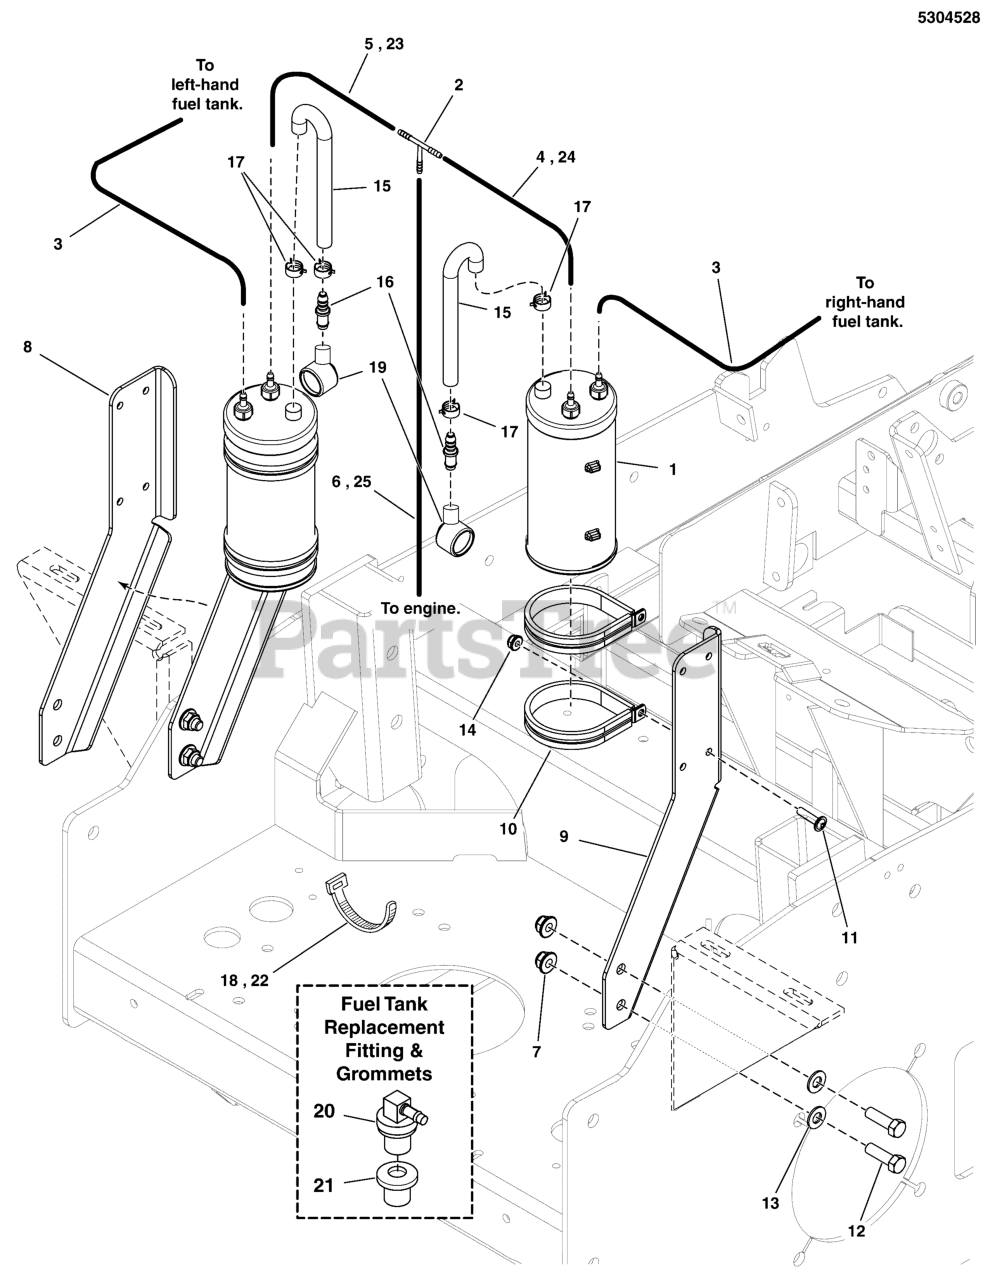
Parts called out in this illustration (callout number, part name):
1	CNSTR, CARB, 6 GAL
2	FITTING, 3/16" TEE, BARB TYPE, HDPE
3	HOSE, VAPOR, 5MM ID, 7.50 LG
4	HOSE, VAPOR, 5MM ID, 49.00 LG
5	HOSE, VAPOR, 5MM ID, 16.50 LG
6	HOSE, VAPOR, 5MM ID, 18.00 LG
7	NUT, 3/8-16 HEX NYLOCK FLANGE
8	BRACKET, EVAP MOUNT, LEFT - BLK
9	BRACKET, EVAP MOUNT, RIGHT - BLK
10	CLAMP, 3" ID, CUSHIONED, STAINLESS
12	BOLT, 3/8-16 X 1-1/4" GD5 CZ
13	WASHER, 3/8 SAE
14	NUT, 1/4-20 HEX NYLOCK FLANGE
15	HOSE, FORMED, EVAP CANISTER
16	FITTING, STRAIGHT, 10MMX10MM, PLASTIC
17	CLAMP, HOSE
18	TIE, SELF-LOCKING, 15"
19	DUST FILTER, CANISTER
20	REMOTE VENT ASSEMBLY
21	GROMMET
22	TIE, SELF-LOCKING, 12"
23	HOSE, VAPOR, 5 MM ID, 50.50 LG
24	HOSE, VAPOR, 5 MM ID, 29.00 LG
25	HOSE, VAPOR, 5 MM ID, 9.00 LG
